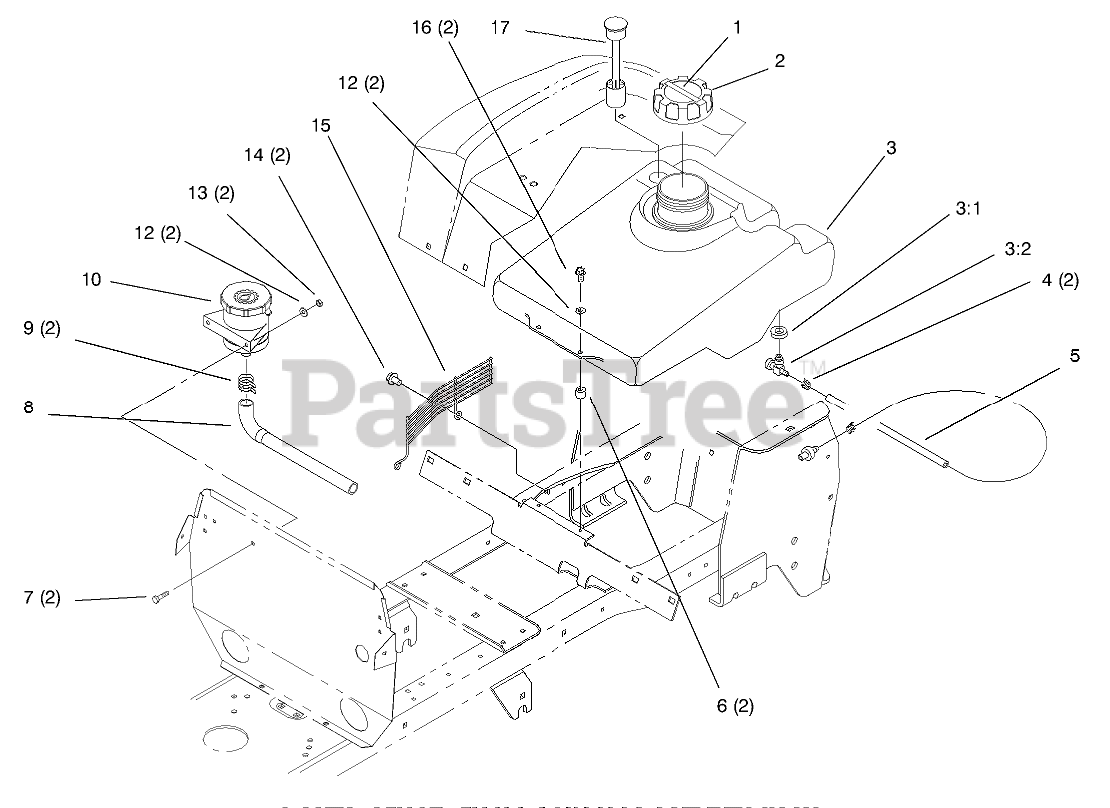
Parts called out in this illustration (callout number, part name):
1	Decal-Oil Check
2	GAS CAP ASM
3	TANK-FUEL
4	CLAMP-HOSE
5	HOSE - FUEL LINE TWIN
6	SPACER - FUEL TANK
7	SCREW-HH
8	HOSE - HYDRO
9	CLAMP-HOSE
10	ASS'Y-RESERVOIR
12	WASHER-FLAT
13	NUT-LOCK, NI
14	SCREW-HWHTF
15	GUARD - FAN
16	SCREW-HH
17	SENSOR-FUEL, LOW
